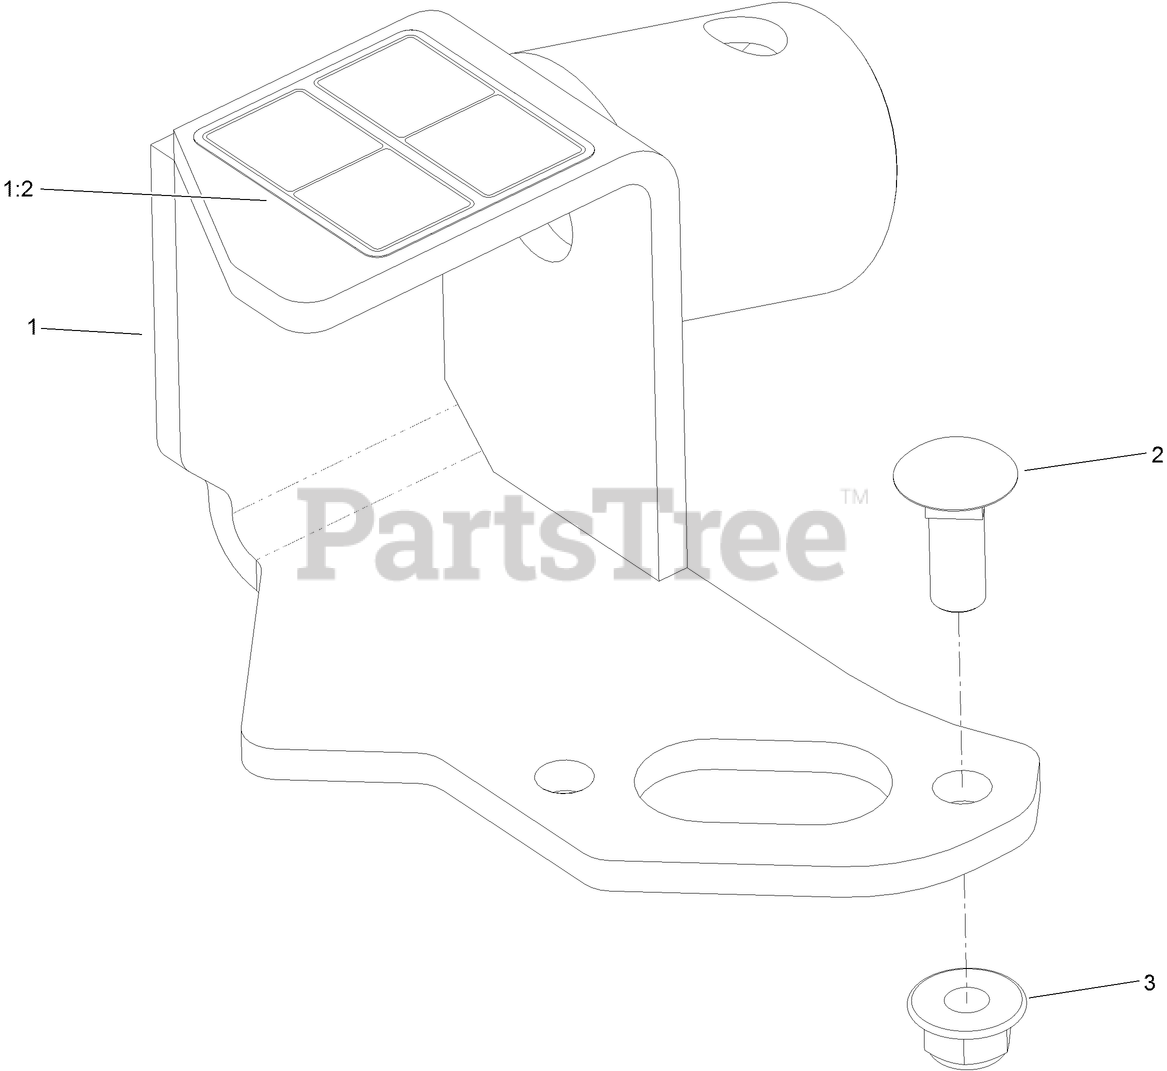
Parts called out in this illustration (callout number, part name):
1:2	DECAL-WARNING, JACK
2	BOLT-CARR
3	NUT-HF, NI
